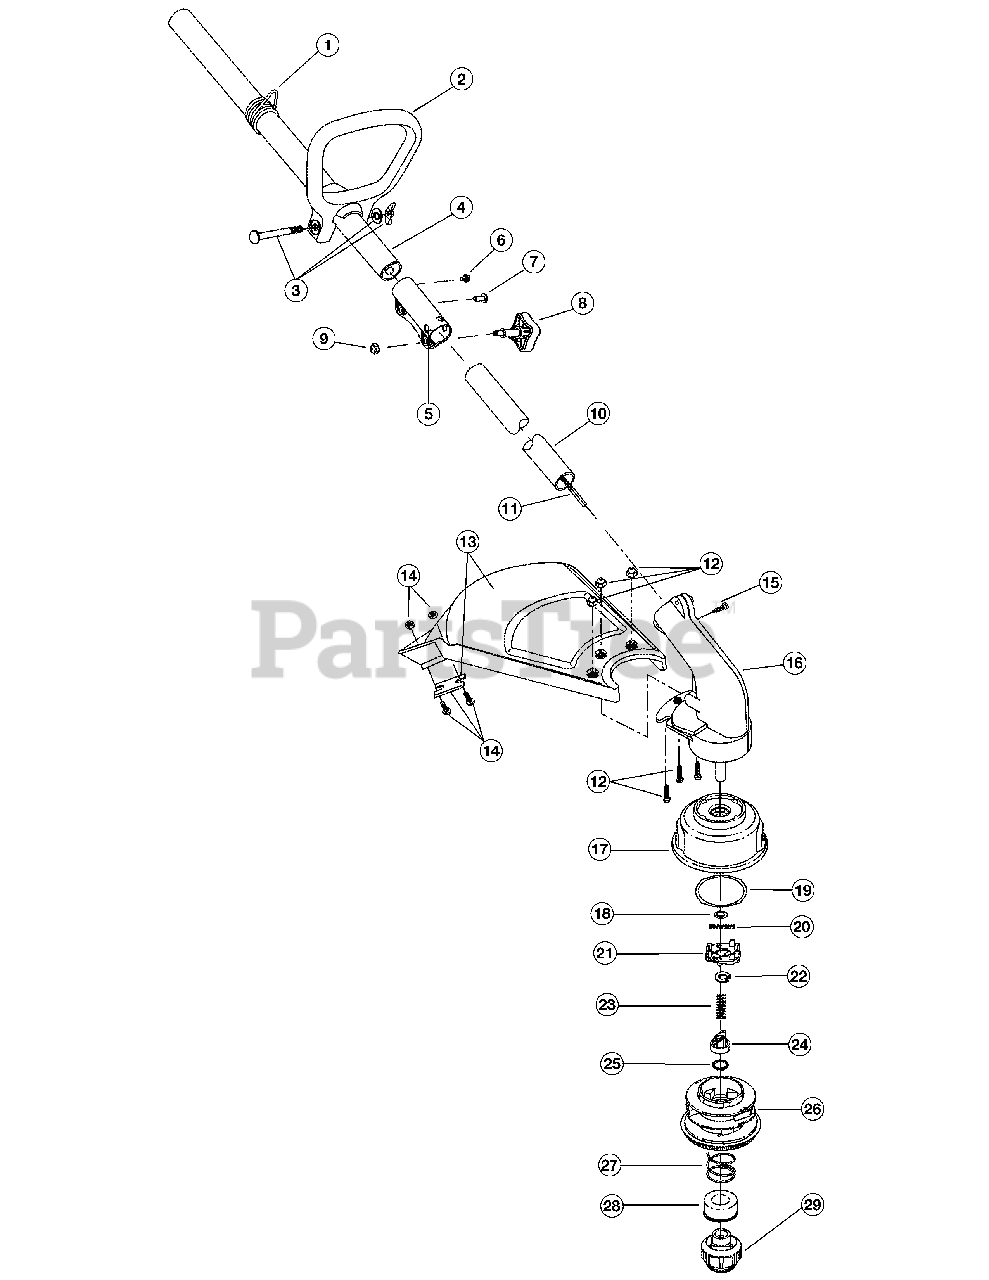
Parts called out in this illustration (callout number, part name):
1	Shoulder Harness Clamp
2	D-Handle
3	D-Handle Hardware Assembly
4	Upper Drive Shaft Housing Assembly
5	Split Boom Coupler (includes 6-9)
8	Adjustment Knob
9	Knob Retaining Nut
10	Lower Drive Shaft Housing Assembly
11	Flexible Drive Shaft
12	Guard Mounting Hardware
13	Guard Assembly
14	Blade Assembly
15	Anti-Rotation Screw
16	Gearbox (includes 17-29)
17	Outer Spool Assembly (includes 18)
18	Retainer
19	Thrust Washer
20	Small Spring
21	Slider
24	Plunger
26	Inner Reel
27	Large Spring
28	Foam Seal
29	Bump Knob Assembly (includes 27 & 28)
